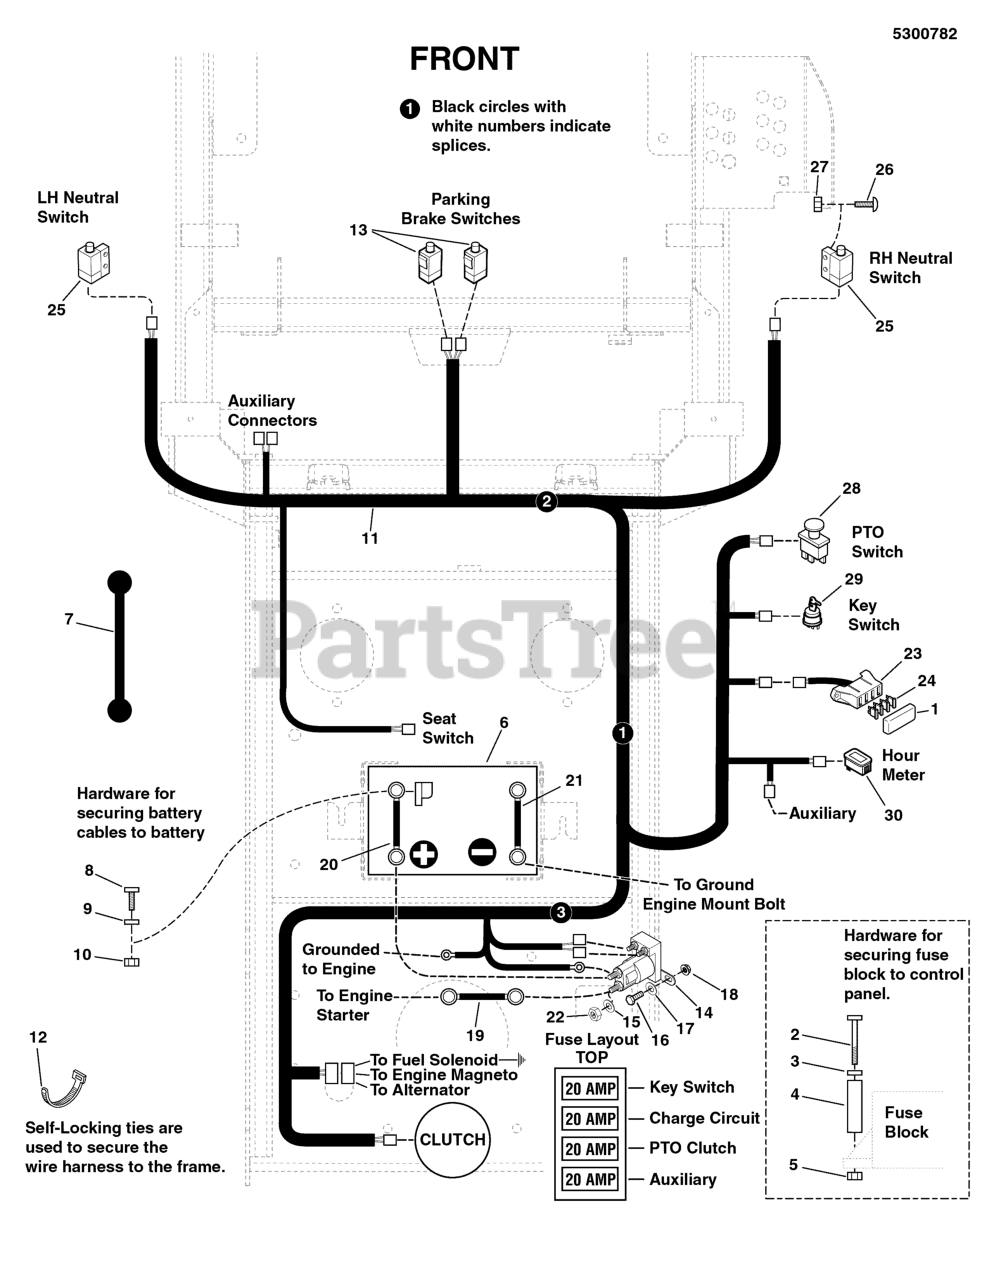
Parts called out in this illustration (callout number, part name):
1	COVER, VINYL FUSEBLOCK
2	SCREW, #10-24 X 2 ROUND PHILLIPS
3	WASHER, #10 SAE
4	SPACER, .20 X .38 X 1.25
5	NUT, #10-24 HEX NYLON LOCK
6	BATTERY, 11U1L, 350 CCA
7	STRAP-BLACK RUBB
8	BOLT, 1/4-20 X 3/4 GD5 YZ
9	WASHER, 1/4 SAE
10	NUT, 1/4-20 HEX SERR. FLANGE
11	WIRE HARNESS, WARNER - IS500Z
12	TIE,SELF-LOCKING, 12"
13	SWITCH, DP NO/NC SNAP-IN
14	SOLENOID-4 POLE 12 VOLT DC (TROMBETTA)
15	WASHER, 5/16 LIGHT LOCK
16	HHCS, 1/4-20 X 0.625, GR5, ZINC/CLEAR
17	WASHER, 1/4 SAE
18	NUT, 1/4-20 HEX SERR. FLANGE
19	BATTERY CABLE, POSITIVE, 22
20	BATTERY CABLE, POSITIVE, 15
21	BATTERY CABLE, NEGATIVE, 10
22	NUT, 5/16-24 JAM
23	WIRE HARNESS, FUSE BLOCK - IS2000
24	FUSE, ATO, 20 AMP
25	SWITCH, PLUNGER, N.O./N.C.
26	SCREW- #10-24 X 1/2 ROUND PHILLIPS
27	NUT, #10-24 HEX
28	SWITCH, BLADE ENGAGEMENT
29	SWITCH, IGNITION, 6 POST
30	HOUR METER
